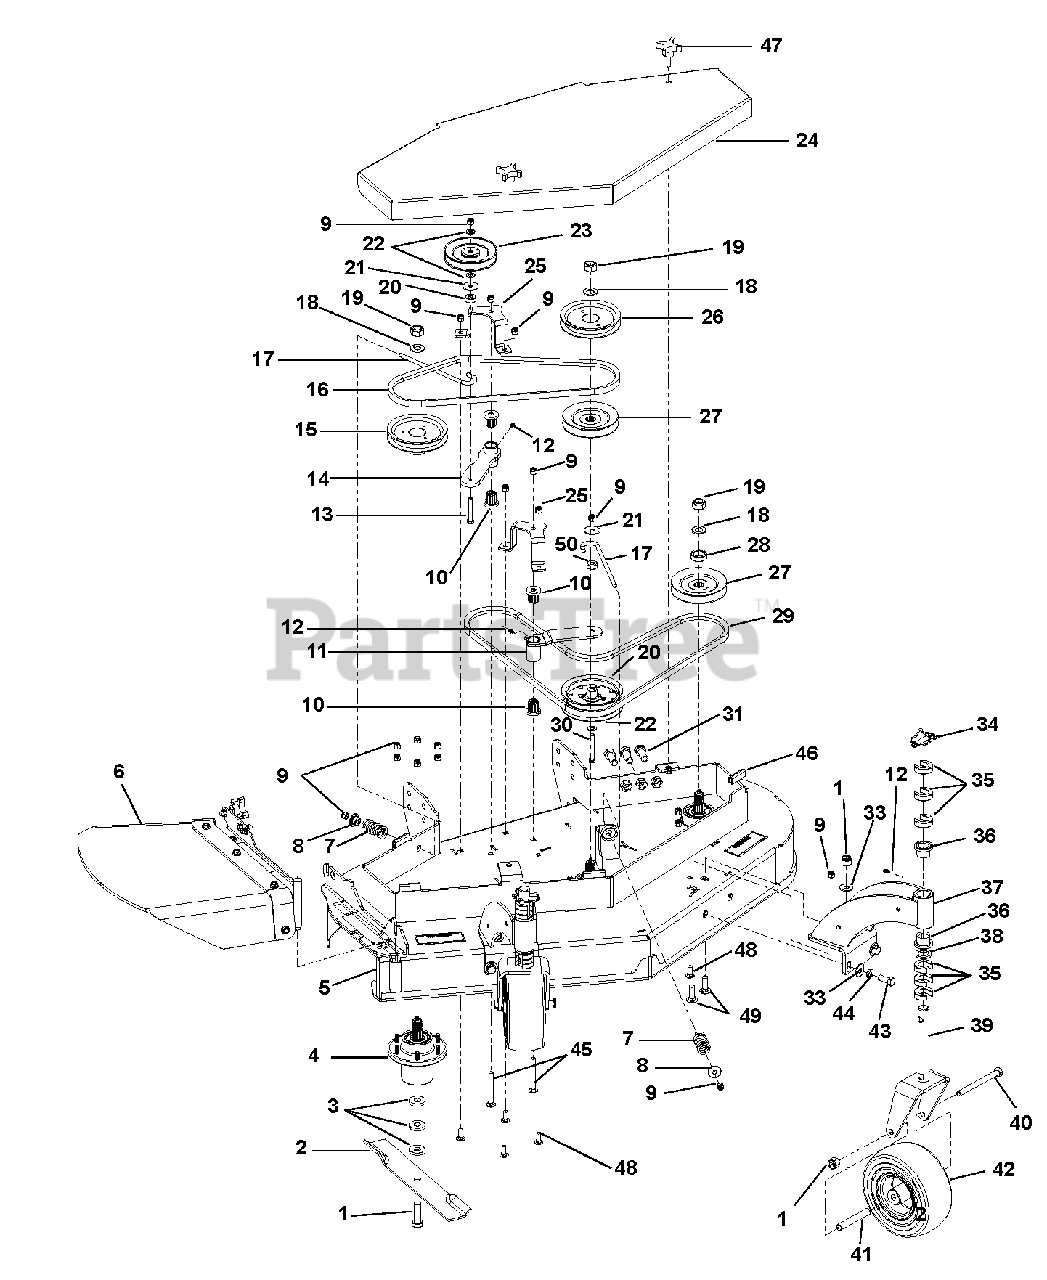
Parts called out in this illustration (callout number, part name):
1	Bolt, .625-11 x 2.00 Hex 8
2	Blade, 16.500 Lo-Lift
3	Washer, Blade
4	Assembly, Spindle Housing
5	48" EverRide Gear Deck with Decals
6	Discharge Shield Assembly
7	Spring, COM 1.22 x .162 x 2.50
8	Keeper, Spring
9	Locknut, .38-16 Nyloc
10	Bearing, Flange M10 x M25 x M27 Fluted
11	Weldment, Idler Arm w/Offset
12	Fitting, .25-28 STRGT Grease Zerk
13	Bolt, .38-16 x 2.50 Hex Grade 5
14	Weldment, Idler
15	Pulley, Spline Spindle Offset
16	Belt, HB 51.4 Elbow AMD
17	J-Bolt, .375-16 x 7.88
18	Washer, .75 x 1.313 x .113
19	Locknut, .75-16 Crown
20	Pulley, Flat 5.00 x .375 w/BRG
21	Washer, Flat .375 x 1.50 x .063
22	Washer, .406 x .813 x .065 Flat
23	Pulley, V-Belt 5.0
24	Weldment, 48" Belt Shield EverRide
25	Bracket, Idler
26	Pulley, Spline Spindle Offset
27	Pulley, Spline Spindle SH
28	Spacer, 1.500 x 1.000 x .510
29	Belt, HB Wrapped 83.2
30	Bolt, .38-16 x 2.75 Grade 5
31	Bolt, Hex .625-11 1.5 Grade 8
32	Locknut, .50-13 Nyloc
33	Washer, .438 Regular Flat
34	Pin, LNC .438 x 2.00
35	C-Spacer, 1.00 x 1.77 x .500
36	Bearing, Flange 1.00 x 1.25 x 1.00
37	Weldment, Strut Front FXWLK w/ EverRide Paint
38	Bushing, 1.03 x 1.50 x .179
39	Weldment, Caster Yoke w/ EverRide Paint
40	Bolt, .50-13 x 5.50 Hex Grade 5
41	Tube, Caster Axle
42	Assembly, Wheel and Tire 9 x 3.5
43	Bolt, .50-13 x 1.25 Hex 5
44	Washer, .500 Medium Spring Lock
45	Bolt, .375-16 x 3.50 Round Head Square Neck Grade 5
46	Trim, 1/4" Trim-LOK
47	Knob, .375 x 1.25-4 Prong
48	Bolt, .38-16 x 1.00 Round Head Square Neck Grade 5
49	Bolt, .50-13 x 1.50 Round Head Square Neck Grade 5
50	Bushing, .380 x 1.00 x .410
